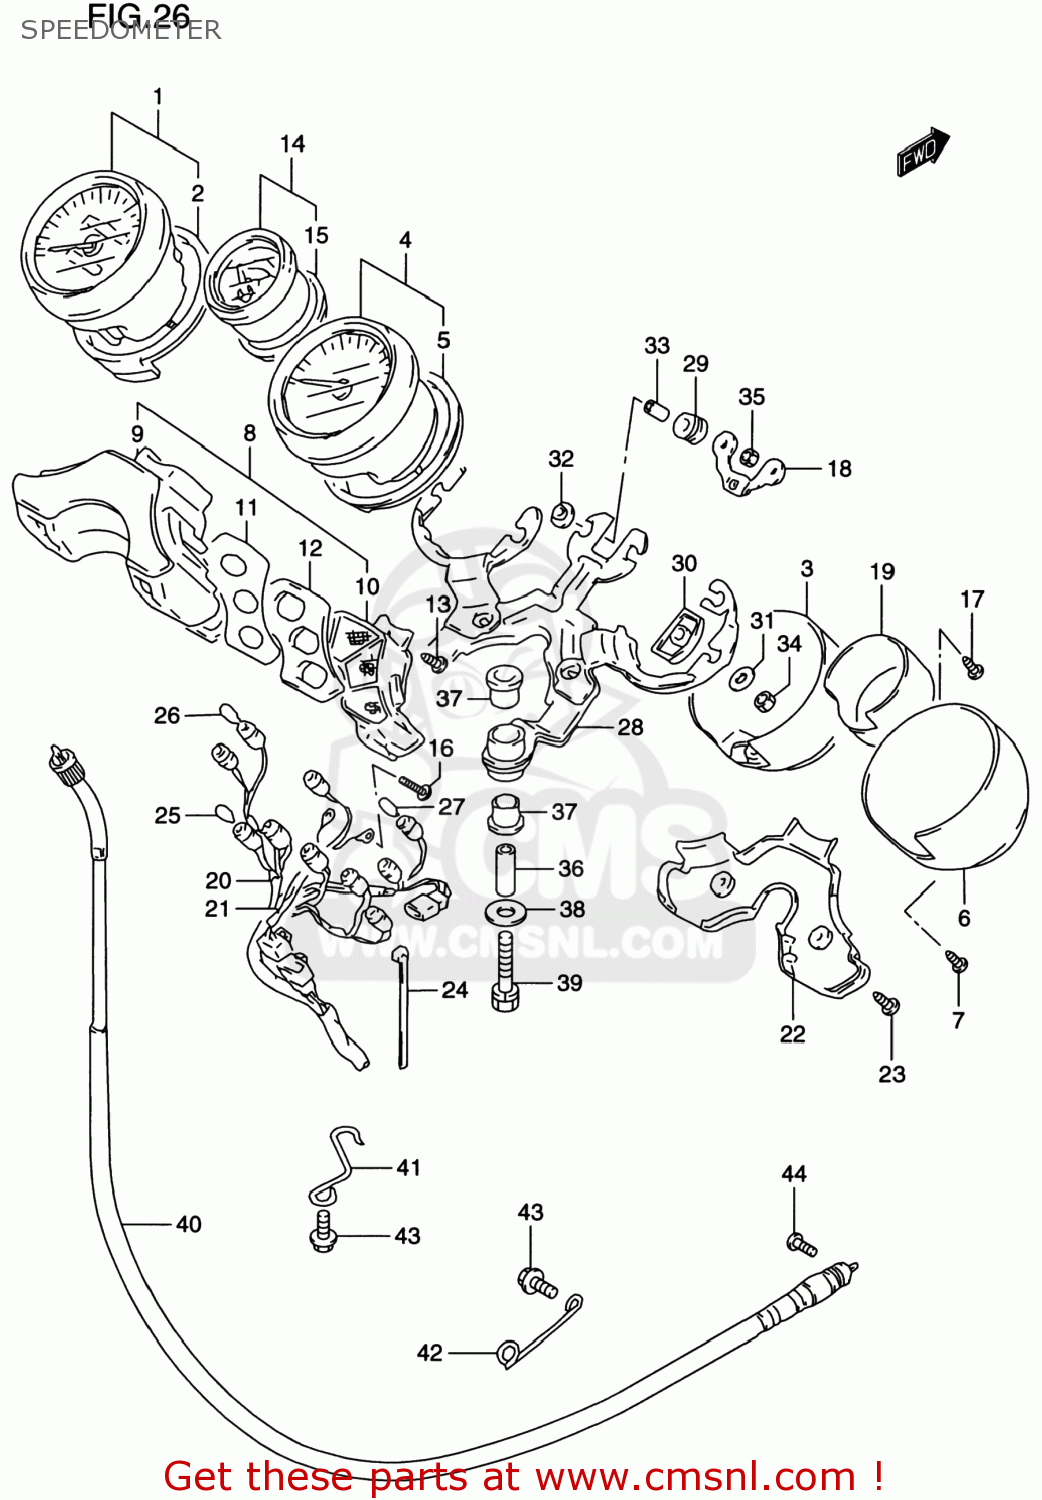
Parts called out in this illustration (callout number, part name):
1	SPEEDOMETER
2	DAMPER
3	COVER,SPEEDOMETER
4	TACHOMETER
5	DAMPER
6	COVER,TACHOMETER
7	SCREW
8	BOX,PILOT
9	CASE,UPR
10	LWR CASE
11	PANEL
12	GASKET
13	SCREW
14	FUEL,METER
15	DAMPER
16	SCREW(3X22)
17	SCREW
18	PLATE,SET
19	COVER,FUEL METER
20	SOCKET,METER
21	SOCKET,FUEL METER
22	COVER,PILOT BOX
23	SCREW
24	CLAMP
25	BULB(12V3W,T6.5)
26	BULB(12V1.7W,T6.5)
27	BULB(12V1.7W,T10,WB121)
28	BRACKET,METER
29	DAMPER
30	DAMPER
31	WASHER(5.2X16X1)
32	WASHER,FUEL,METER
33	SPACER,FUEL METER
34	NUT
35	NUT
36	BUSH(L:31)
37	CUSHION
38	WASHER (8.5X26X1.6)
39	BOLT
40	CABLE ASSY,SPEEDOMETER
41	GUIDE,SPEEDOMETER CABLE NO.1
42	GUIDE,SPEEDOMETER CABLE NO.3
43	BOLT
44	SCREW
